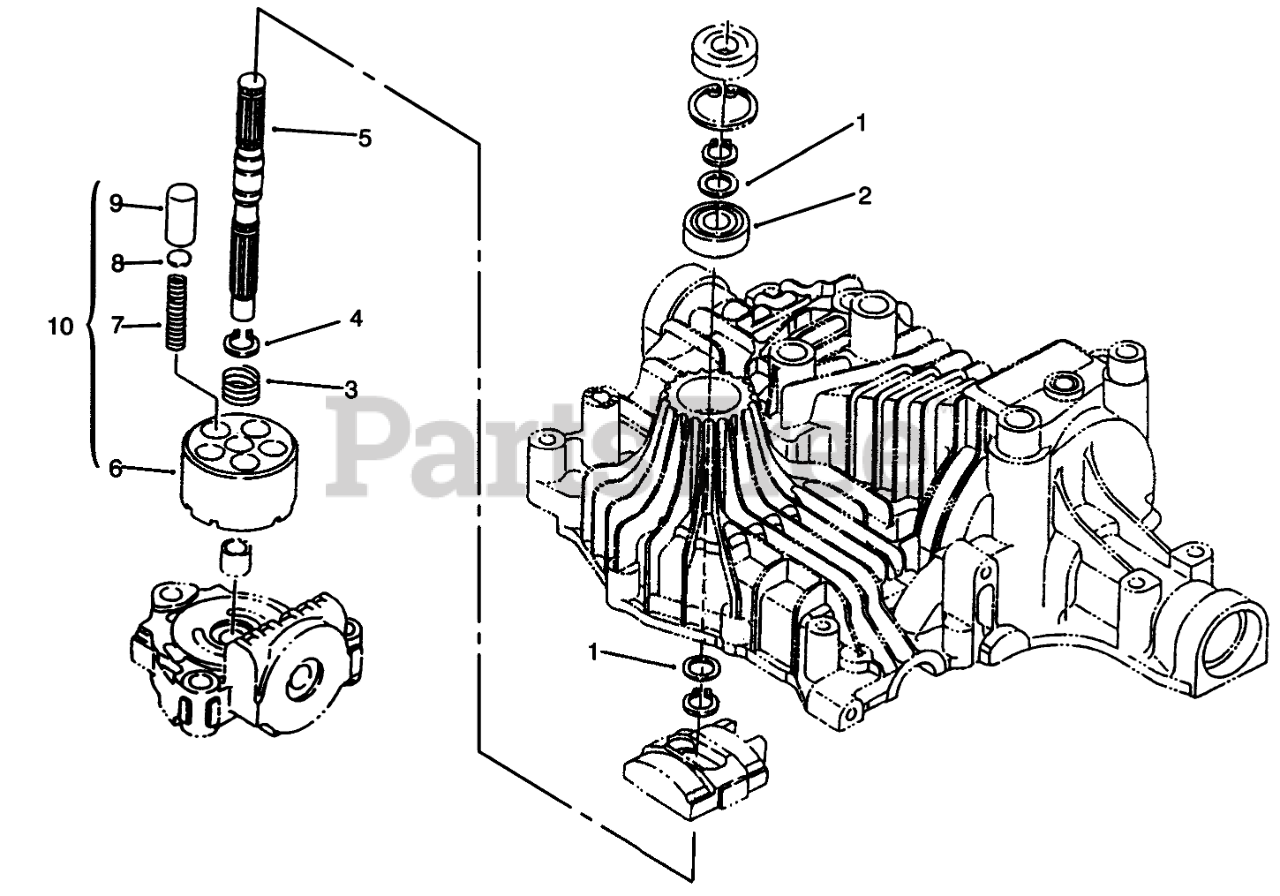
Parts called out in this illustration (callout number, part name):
1	Washer (Only On: 72043, 72063, 72103)
2	Bearing-Ball (Only On: 72043, 72063, 72103)
3	Spring (Only On: 72043, 72063, 72103)
4	Ring-Snap (Only On: 72043, 72063, 72103)
5	Shaft-Pump (Only On: 72043, 72063, 72103)
10	Cylinder ASM INCL 6-9 (Only On: 72043, 72063, 72103)
